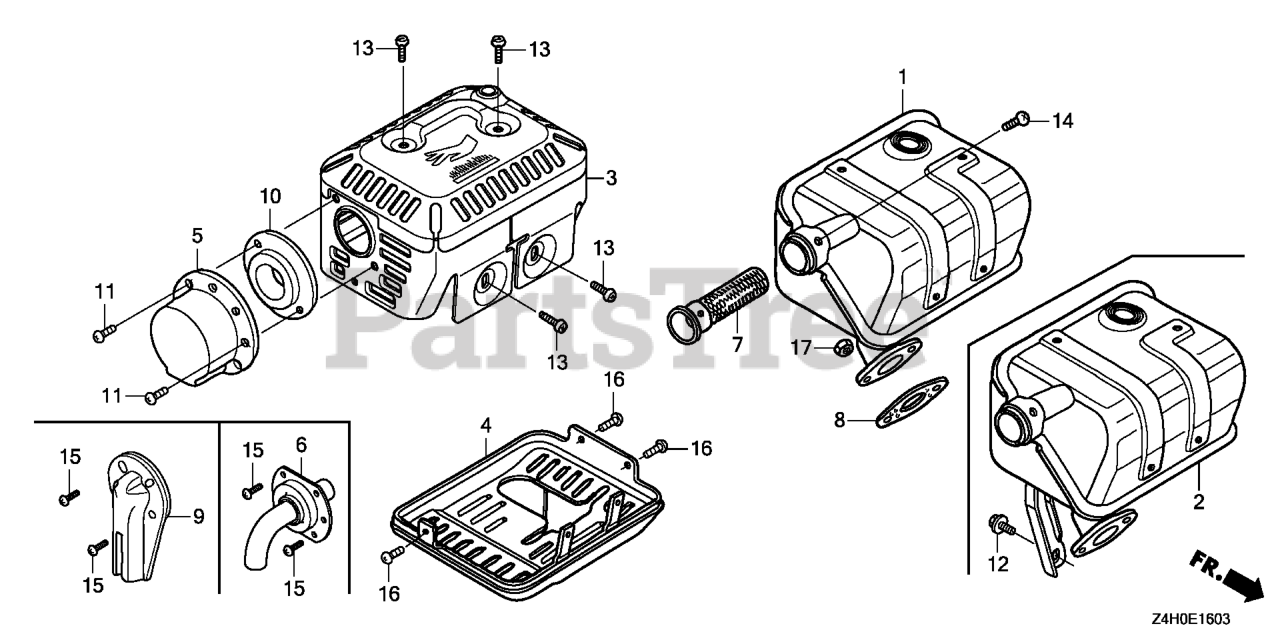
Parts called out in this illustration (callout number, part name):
1	MUFFLER
1	MUFFLER (ARRESTER)
3	PROTECTOR, MUFFLER (STD)
7	ARRESTER, SPARK
8	GASKET, MUFFLER
13	SCREW, TAPPING (5X8)
14	SCREW, TAPPING (4X6) (TO INSTALL OPTIONAL SPARK ARRESTER)
17	NUT, HEX. (8MM)
